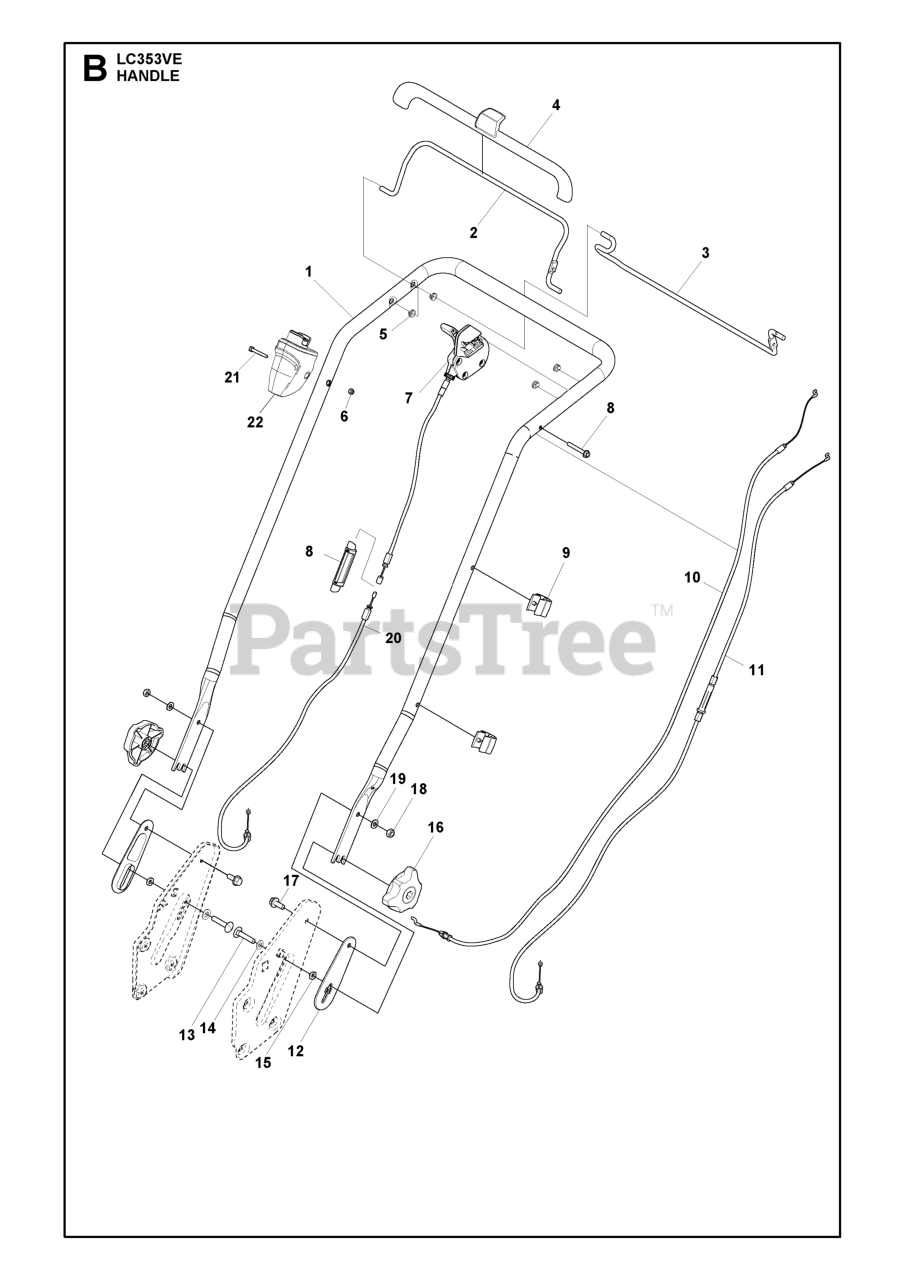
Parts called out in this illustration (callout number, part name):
6	NUT FLANGE - M6
15	NUT ML6M M8
18	LOCKNUT M8
21	Hex Head Capscrew, M6 X 1.00 X 40MM
